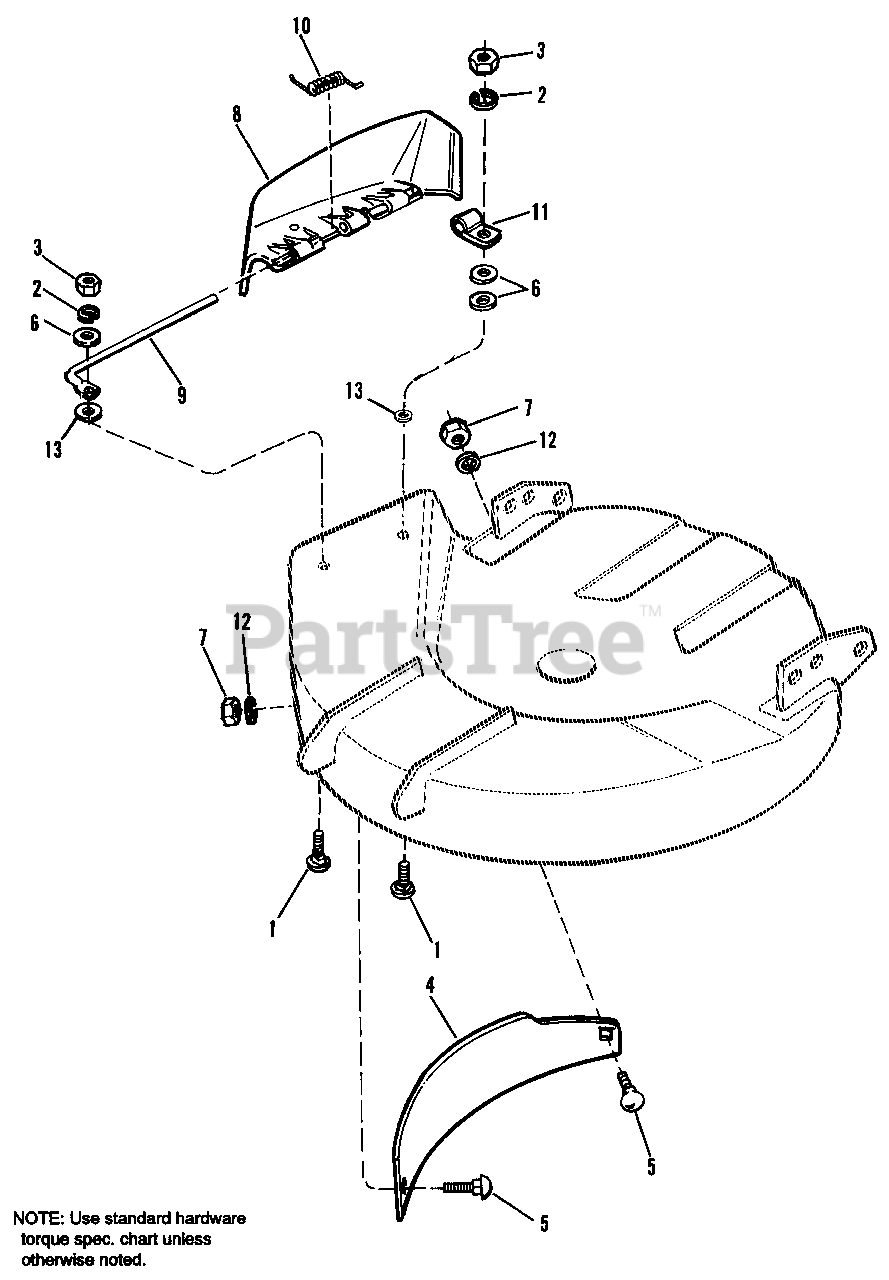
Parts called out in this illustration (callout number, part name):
1	CARRIAGE BOLT, 1/4-20 x 1-1/4
2	LOCKWASHER, 1/4
3	NUT, Hex, 1/4-20
4	PLATE, Discharge (30" Mulcher)
5	CARRIAGE BOLT, 5/16-18 x 5/8 (30" Mulcher)
6	WASHER, Plain
7	NUT, Hex, 5/16-18 (30" Mulcher)
8	DEFECTOR, Plastic
9	ROD, Deflector, Front
12	LOCKWASHER, 5/16 (30" Mulcher)
13	PUSHNUT, 1/4
